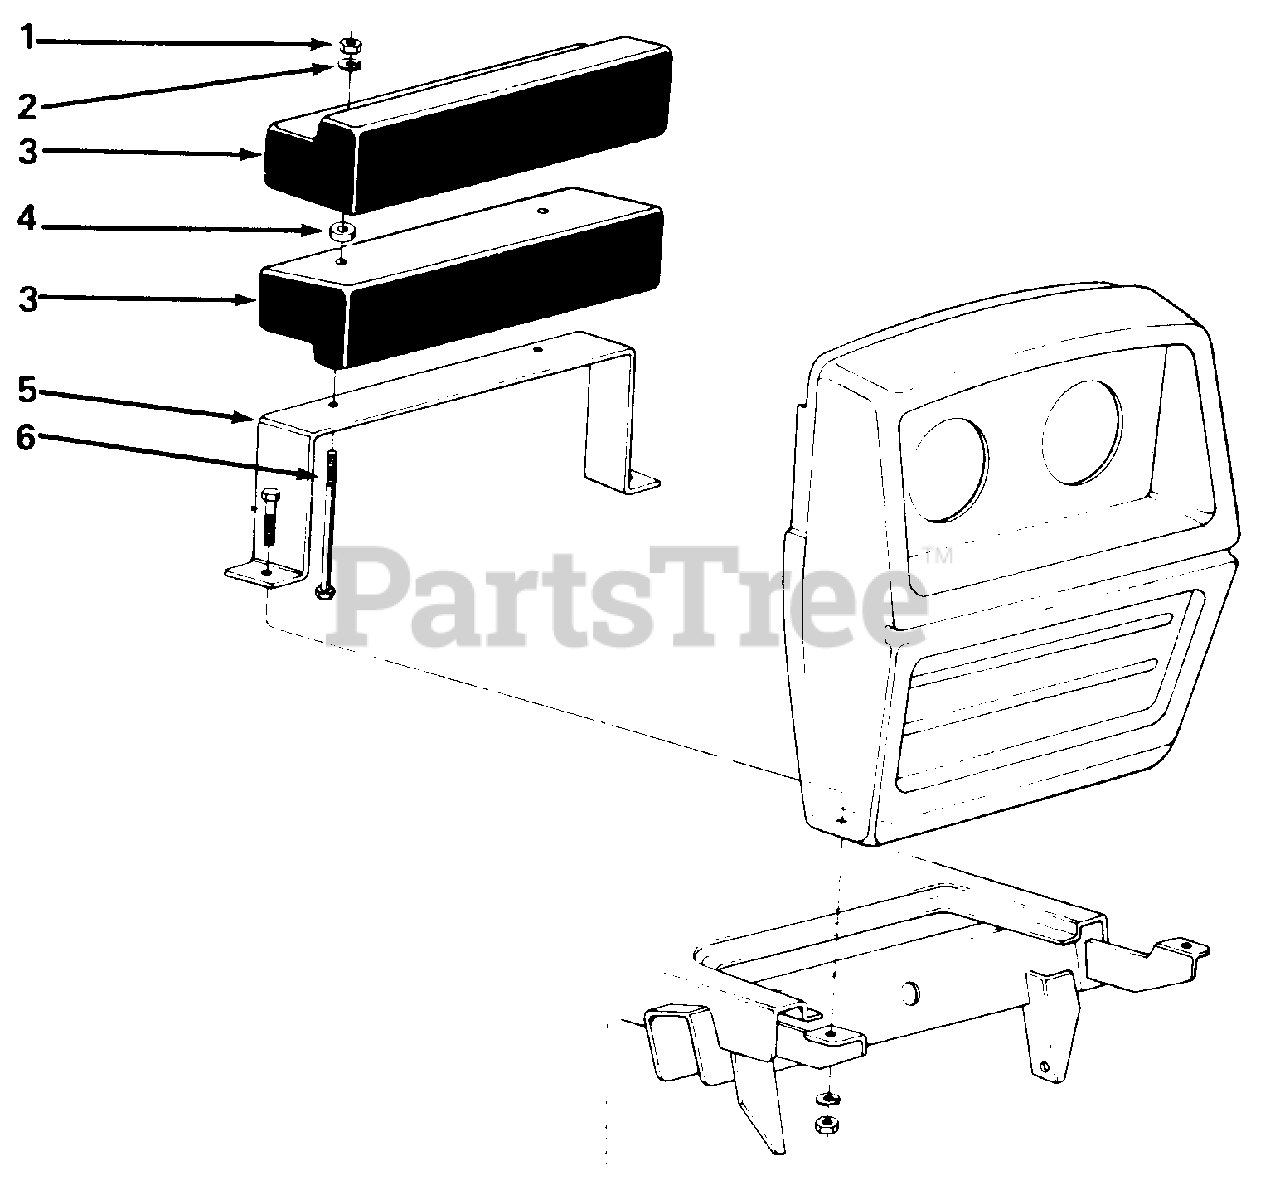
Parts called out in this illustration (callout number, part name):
1	Hex Nut 3/8-16 Thd.* 2
2	L.-Wash. 3/8 I.D.* 2
3	Weight-35 Ib. 2
4	Spacer 2
5	Front Weight Bracket
6	Hex Bolt 3/8-16 x 6.5" Lg. 2
